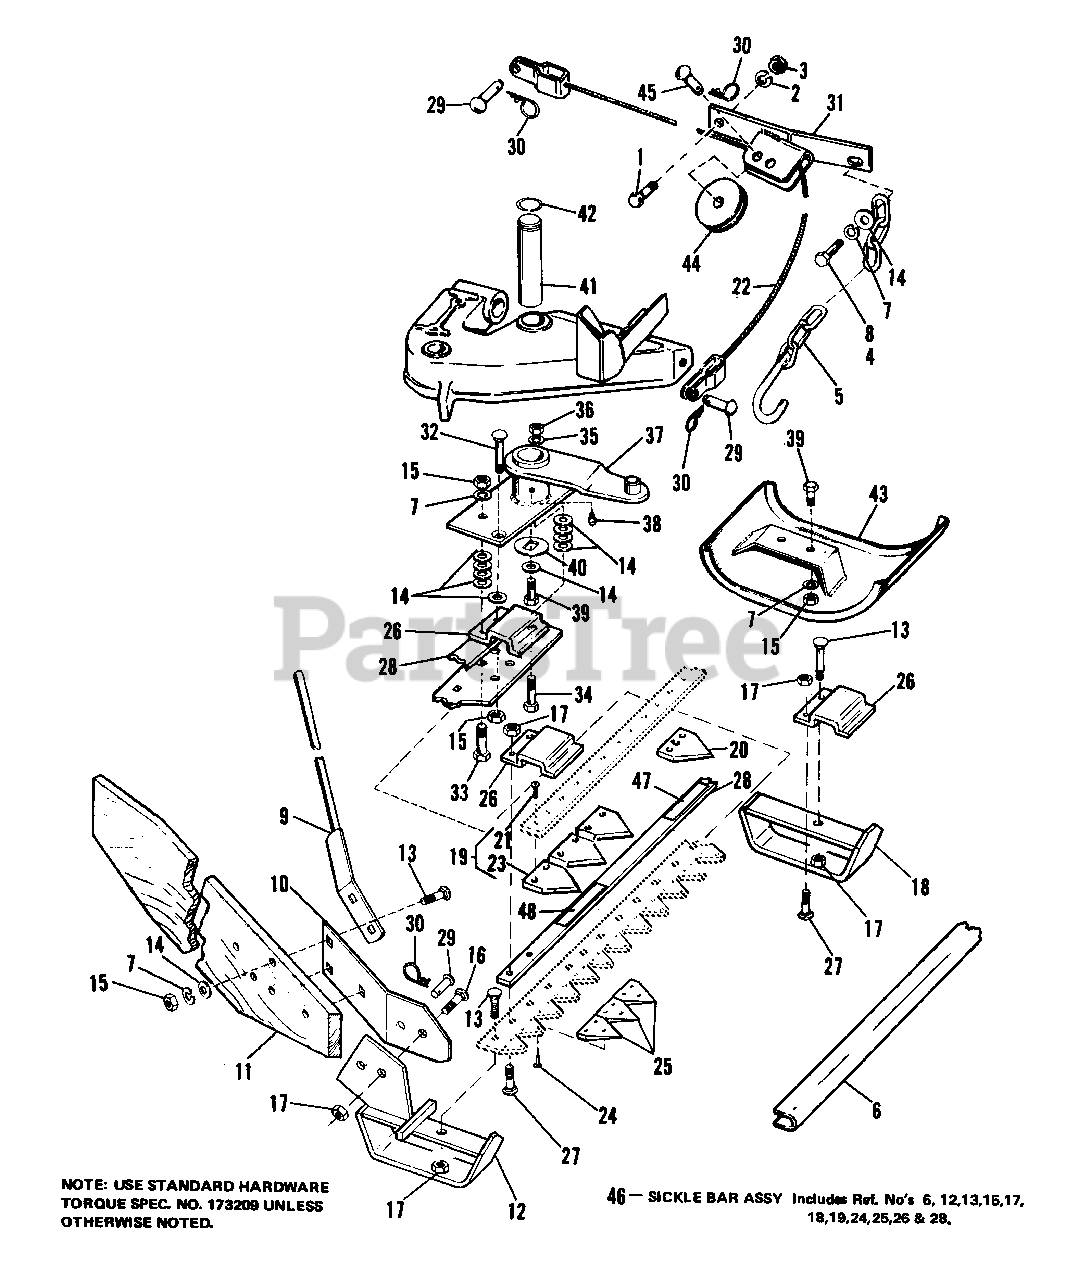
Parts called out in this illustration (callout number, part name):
1	CAPSCREW, Hex Hd., /16-18 x 1
2	LOCKWASHER, 5/16
3	NUT, Hex, Full, 5/16-18
4	CAPSCREW, Hex Hd., 5/16-18 x 1-1/4
5	CHAIN & HOOK ASSY
6	SHIELD, Knife
7	LOCKWASHER, 3/8
8	CAPSCREW, Hex Hd., 3/8-16 x 1-1/4
9	ROD ASSY, Divider
10	SUPPORT, Divider Board
11	BOARD, Divider
12	SHOE ASSY, Outer
13	BOLT, Carriage, 3/8-16 x 1-1/2
14	WASHER, Plain, 3/8
15	NUT, Hex, Full, 3/8-16
16	BOLT, Shoulder, 3/8-16 x 1
17	LOCKNUT, Hex, 3/8-16
18	SHOE ASSY, Center
19	KNIFE ASSY, Riveted
20	KNIFE, Section, 3 Hole
21	RIVET, Flat, No. 6 x 1/2
22	CABEL ASSY
23	KNIFE, Section, 2 Hole
24	SCREW, Self-Tapping
25	PLATE, Ledger, Smooth
26	CLIP, Hold Down
27	BOLT, Carriage, 3/8-17 x 1-1/4
28	STRAP, Wear
30	CLIP, Spring
31	MOUNTING ASSY, Pulley
32	BOLT, Plow, 3/8-16 x 1-3/4
33	CAPSCREW, Hex Hd., 3/8-16 x 1-1/2
34	CAPSCREW, Hex Hd., 7/16-14 x 1-1/2
35	LOCKWASHER, 7/16
36	NUT, Hex, Full, 7/16-14
37	LEVER ASSY, Cutter Bar
38	FITTING, Grease
39	CAPSCREW, Hex Hd., 3/8-16 x 1
40	WASHER, Special
41	SHAFT, Cutter Bar
42	RING, Retaining
43	SHOE ASSY
46	BAR ASSY, Sickle (Incl. Ref. No's. 6, 12, 13, 15, 17, 18, 19, 24, 25, 26, & 28)
47	DECAL, Safety First
48	DECAL, Engine Shut Off
